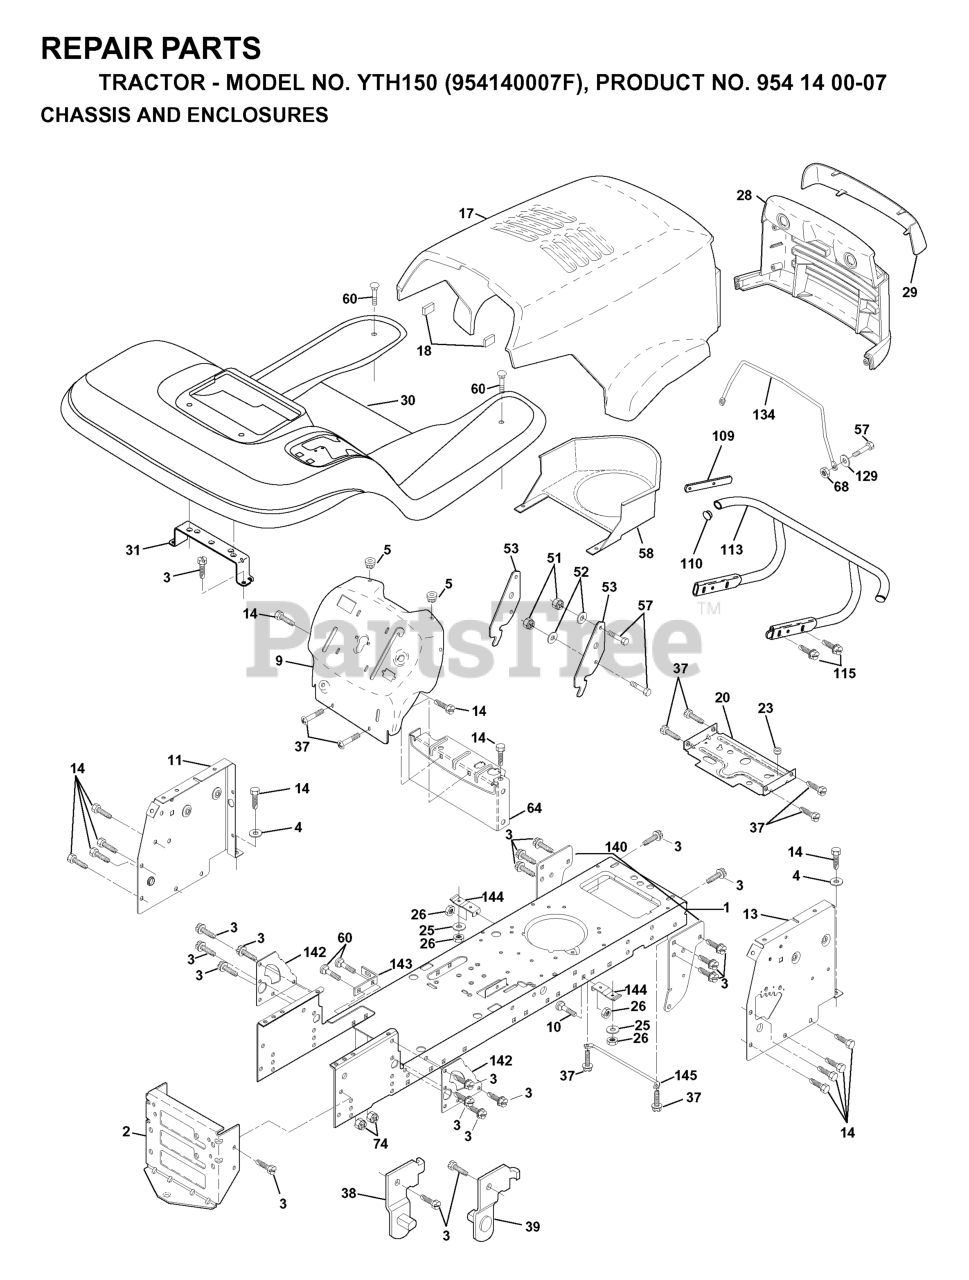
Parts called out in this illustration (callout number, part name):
2	STRETCH DRAWBAR
3	SCREW
4	Washer 13/32 X 3/4 X 16 Ga.
5	BUMPER.RUBBER.HOOD
9	DASH PANEL
10	BOLT D
11	PANEL DASH LH
14	SCREW LT
17	HOOD - LT/YT
18	BUMPER HOOD T
20	PLATE MTG
23	BUSHING.SNAP.NYL.BLK.
25	WASHER
26	NUT
28	GRILLE LT/PL HUSQVARNA
29	LENS LT/PL HUSQVARNA
30	FENDER FOOTREST
31	BRACKET.SUPPORT.FENDER
37	Screw 5/16-18 x 1/2 Hex, Self Tapping 5/16-18 x 1/2
38	BRACKET LH PIVOT
39	BRACKET RH PIVOT
51	LOCKNUT.NYLOC.1/4-20
52	WASHER
53	BRACKET PNT PICK OFF LT/PL
57	BOLT
58	AIR DUCT P/L/LT
60	Bolt - Rd. Hd. Sq. Neckiage 3/8 16 x 3/4
64	DASH LOWER
68	NUT
71	NUT.CROWNLOCK.1/4
109	BRACKET BUMPER
110	PLUG PLASTIC
115	SCREW
129	WASHER
134	ROD SUPPORT HOOD LT/PL HUS.
140	BRACKET SUSPENSION FRONT
142	PLATE REINFORCEMENT
143	BRACKET, SWAY BAR
144	BRACKET FOOTREST
145	ROD PIVOT CHASSIS/HOOD
